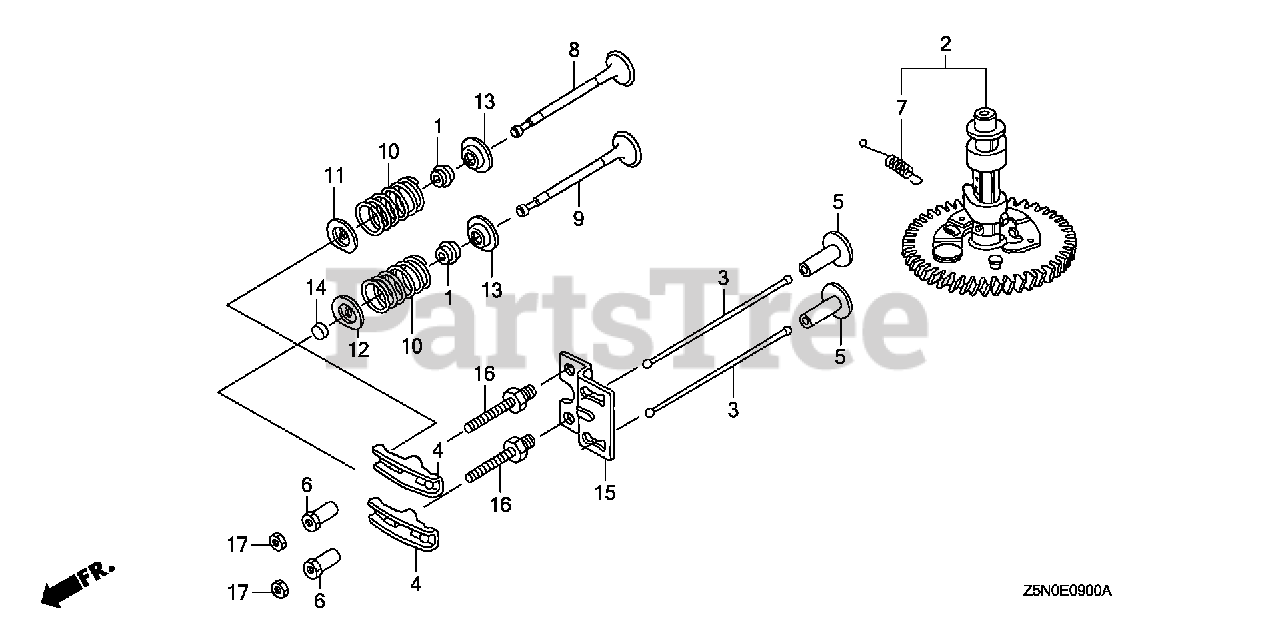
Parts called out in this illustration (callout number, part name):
1	SEAL, VALVE STEM
2	CAMSHAFT ASSY.
4	ARM, VALVE ROCKER
5	LIFTER, VALVE
6	PIVOT, ROCKER ARM
7	SPRING, WEIGHT RETURN
8	VALVE, IN.
9	VALVE, EX.
10	SPRING, VALVE
11	RETAINER, IN. VALVE SPRING
12	RETAINER, EX. VALVE SPRING
13	SEAT, VALVE SPRING
14	ROTATOR, VALVE
15	GUIDE, PUSH ROD
16	BOLT, PIVOT (8MM)
17	NUT, PIVOT ADJUSTING
